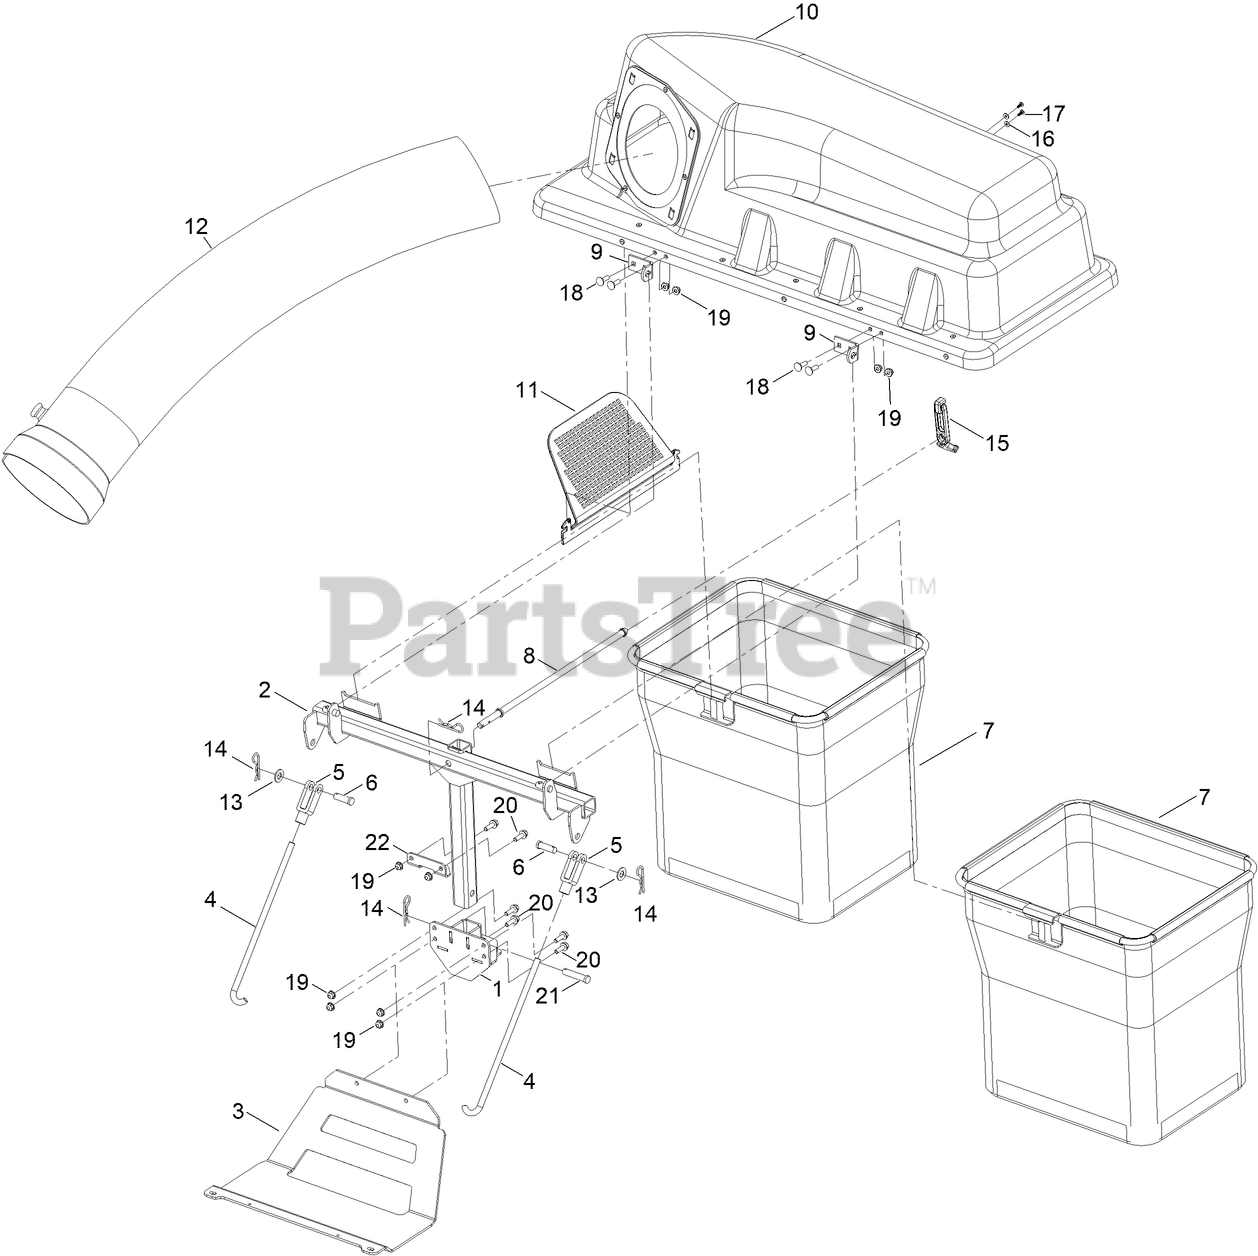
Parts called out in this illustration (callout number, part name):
1	MOUNT-BAGGER [BLACK]
2	FRAME-BAGGER [BLACK]
3	GUARD-MUFFLER [BLACK]
4	ROD-BAGGER SUPPORT
5	CLEVIS
6	PIN-CLEVIS
7	BAG ASM
8	ROD-HOLD DOWN
9	BRACKET-HOPPER PIVOT
10	TOP ASM-BAGGER
11	SCREEN-BAGGER
12	TUBE-BAGGER
13	WASHER-FLAT
14	PIN-HAIR
15	LATCH-RUBBER
16	WASHER-PLAIN
17	SCREW-PLASTIC, PTH
18	BOLT-CARR
19	NUT-HF
20	SCREW-HHF
21	PIN-CLEVIS
22	PLATE-BAGGER STABILIZER
